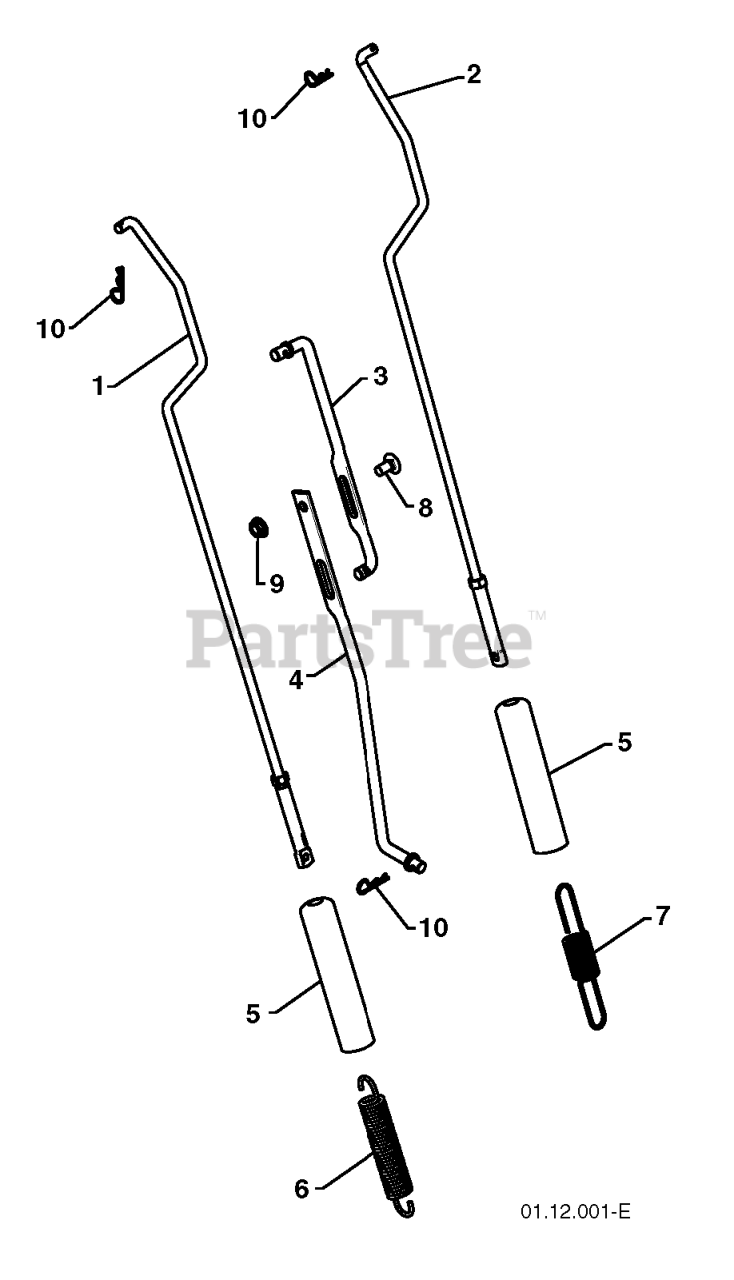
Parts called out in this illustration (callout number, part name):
1	ROD.ASM.IMPELLER
2	ROD.ASM.TRACTION
3	ROD, UPPER SPEED CONTROL
4	ROD, LOWER SPEED CONTROL.SNOW
5	SLEEVE, SPRING
6	SPRING, AUGER CONTROL
7	SPRING, TRACTION DRIVE
8	BOLT
9	NUT.FLANGE.5/16
10	SPRING RETAINER
